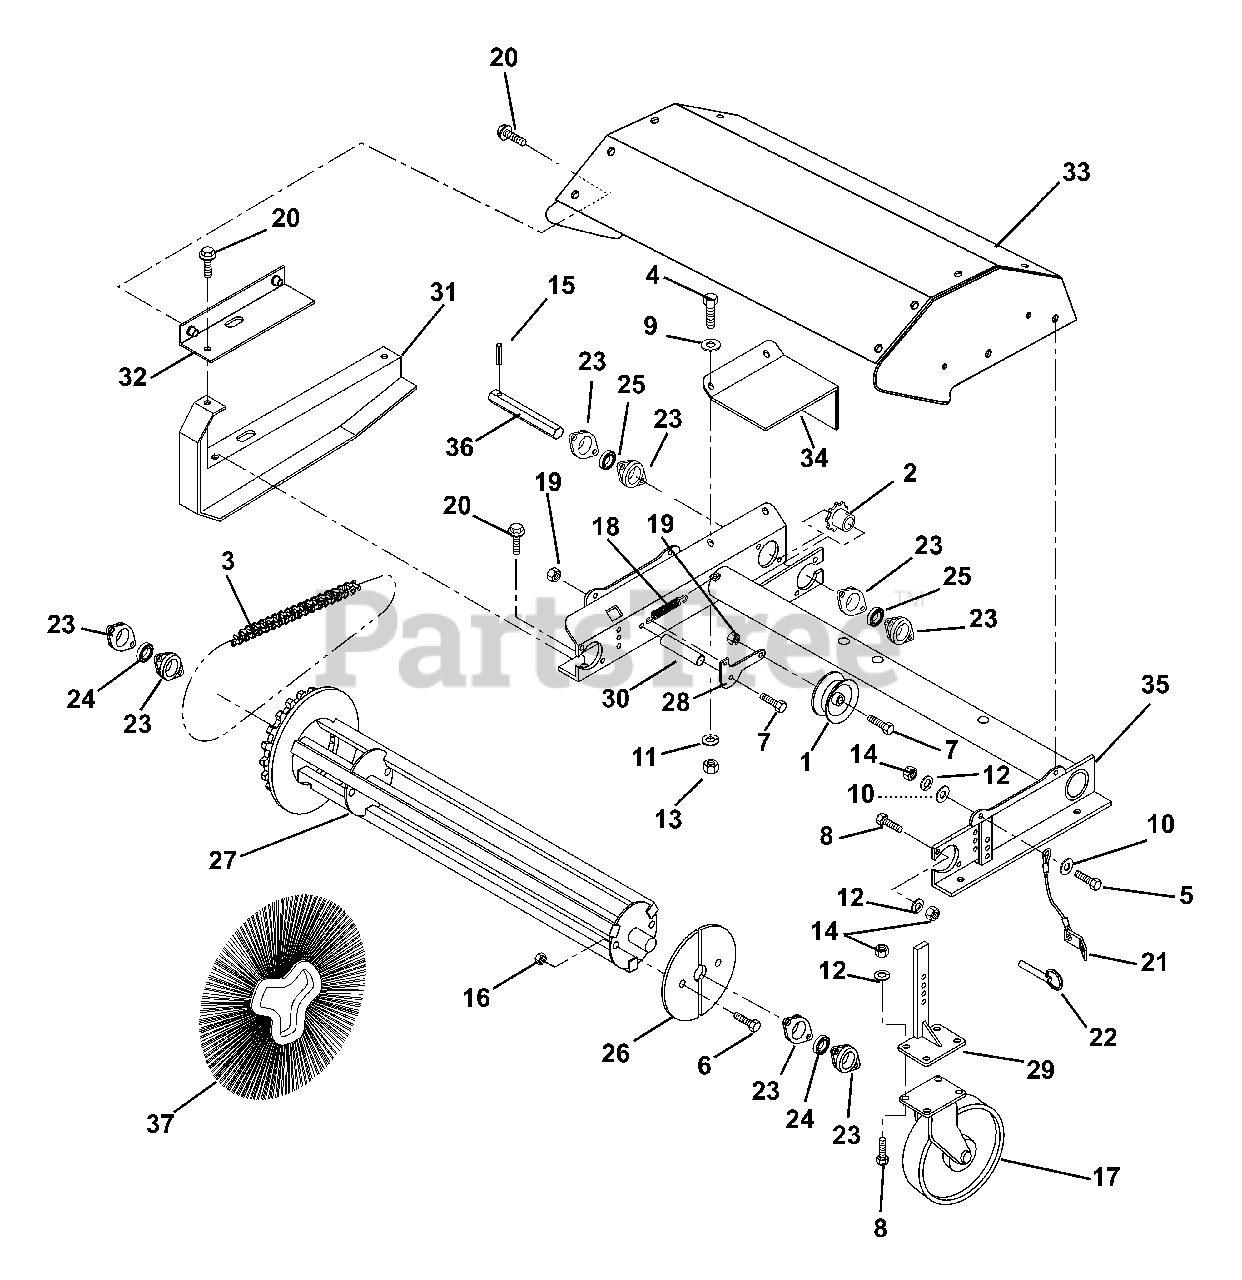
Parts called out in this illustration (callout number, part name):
1	Chain Tightener
2	Sprocket
3	Chain, Assembly #40 x 106
4	Bolt, Hex .25-20 x .75 Grade 5
5	Bolt, Hex .31-18 x 1.00 Grade 5
6	Bolt, Hex .31-18 x 2.25 Grade 5
7	Bolt, Hex .38-16 x 1.50 Grade 5
8	Bolt, Hex .31-18 x .75 Grade 5
9	Washer, Flat Steel .28 x .62 x .065
10	Washer, Flat Steel .31 x .73 x .065
11	Washer, Lock .25 x .062 Regular
12	Washer, Lock .31 x .078 Regular
13	Nut, Hex .25-20
14	Nut, Hex .31-18
15	Pin, Spring Lok .19 x 1.25
16	Nut, Lok Stamped .31-18
17	Wheel, 5 inch Diameter
18	Spring, Tension
19	Nut, Locking Center .38-16
20	Screw, Gear 10.9 M6 x 1-20
21	Lanyard Cable
22	Pin, Spring Ball .375 x 1.00
23	Flange, Spherical
24	Bearing, Spherical
25	Bearing, Ball
26	Retainer Plate
27	Weldment, Core
28	Arm, Idler
29	Weldment, Caster Leg
30	Bushing .62 x 12 Gauge x .75
31	Shield, Chain
32	Shield Chain Top
33	Weldment, Faceted Hood
34	Shield, Input
35	Weldment, Broom Frame
36	Shaft, Hex with Hole
37	Set, 24 Section
